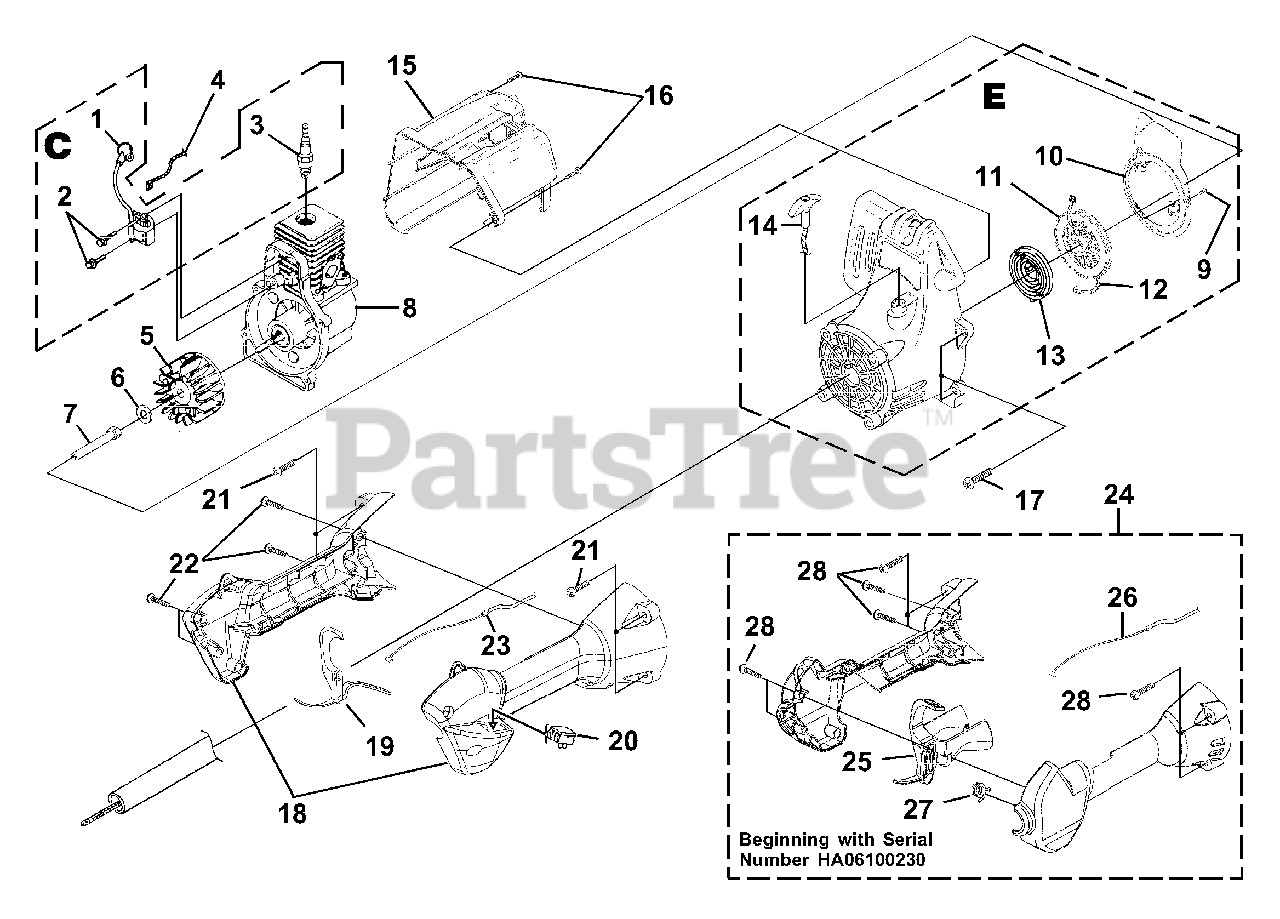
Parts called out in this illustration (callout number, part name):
1	TERMINAL & COVER
2	SCREW-Taptite (8-32 X 1")
3	SPARK PLUG
4	LEAD-Electrical
5	ROTOR KIT
6	WASHER-Flat
7	CONNECTOR-Drive (.250)
8	SHORT BLOCK
9	SCREW-Thread Form (8-16 X 1/2")
10	BAFFLE-Air
11	PULLEY-Starter
12	ROPE-Starter (42")
13	SPRING & CONTAINER
14	GRIP-Starter (Yellow)
15	HOUSING-Rear Kit
16	SCREW-Taptite (10-14 X 3/4")
17	SCREW-Taptite (10-24 X 3/4")
18	CONTROL HANDLE ASSY.
19	TRIGGER-Throttle
20	PLUG-Switch
21	SCREW-Taptite (10-14 X 7/8")
22	SCREW-Truss Hd. (10-14 x 1")
23	CABLE-Throttle
24	CONTROL HANDLE ASSY.
25	TRIGGER
26	CABLE-Throttle
27	SPRING
28	SCREW-Truss Hd. (10-14 x 1")
C	IGNITION KIT
E	COMPLETE STARTER ASSEMBLY
